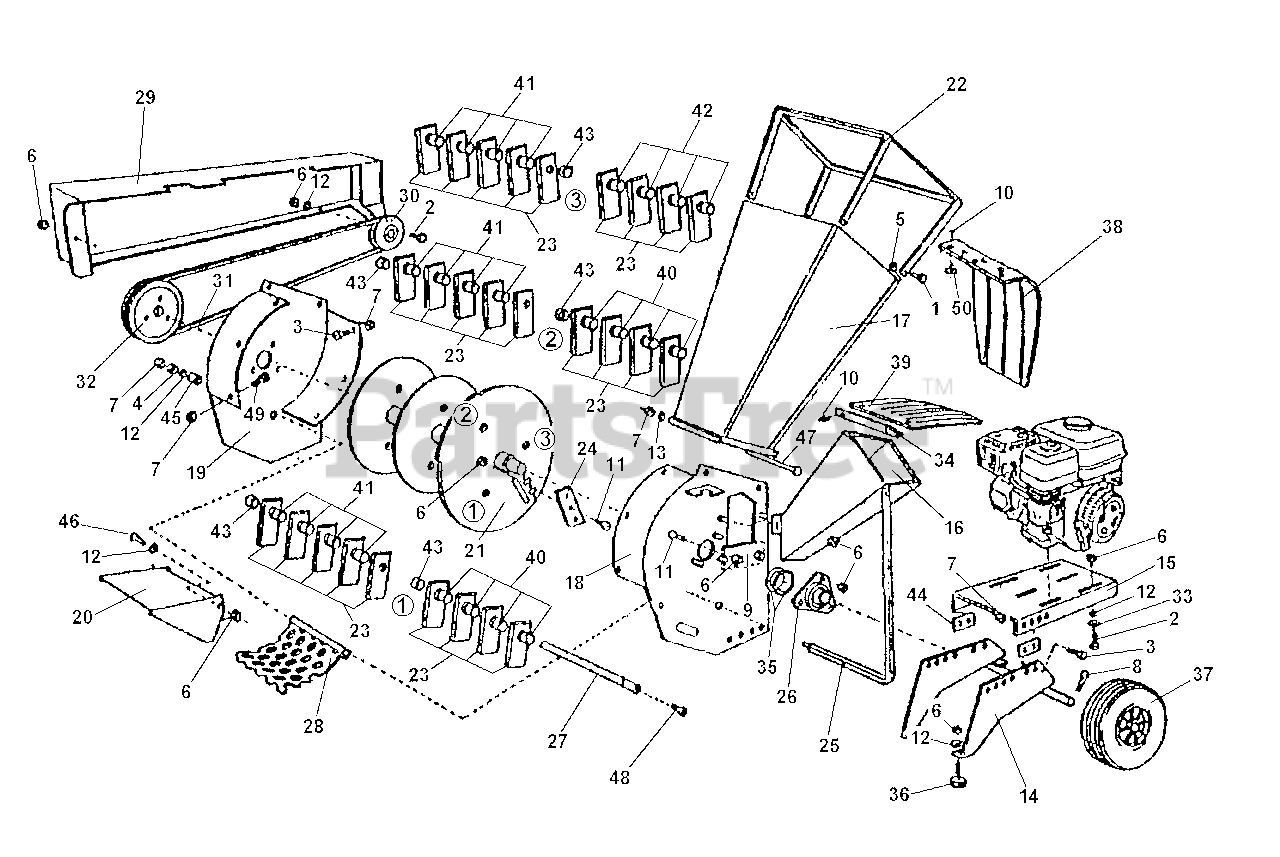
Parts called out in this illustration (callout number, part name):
1	SCREW M6X16
2	SCREW M8X40
3	SCREW M10X25
5	NUT, SELF LOCKING M6
6	NUT, SELF LOCKING M8
7	NUT, SELF LOCKING M10
9	STATIONARY BLADE
10	RIVET 4.9X16
11	Counter Sunk Bolt, M8x25
15	ENGINE SUPPORT
16	CHIPPER CHUTE
18	RIGHT SIDE WALL
19	LEFT SIDE WALL
25	SCREEN LEVER
36	RUBBER FOOT
46	SCREW M8X20
47	SCREW M10X20
48	SCREW M10X15
49	SCREW M10X16
50	FLAT WASHER
